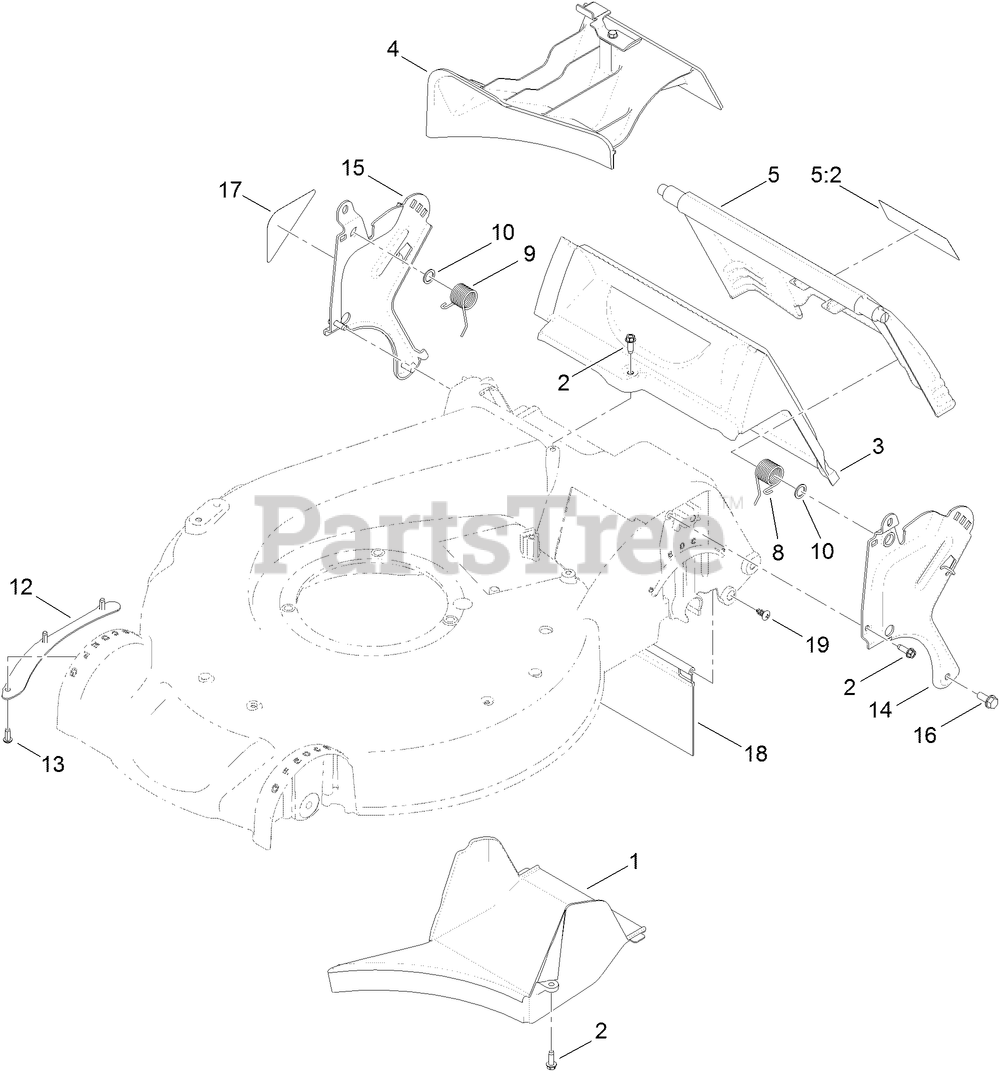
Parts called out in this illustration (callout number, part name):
1	TUNNEL-DISCHARGE
2	SCREW-HWHTF
4	MULCH PLUG ASM
5:2	DECAL-WARNING
8	SPRING-TORSION
9	SPRING-TORSION
10	WASHER-NYLON
12	SHEET-LIP
13	SCREW
14	BRACKET-HANDLE, LH
15	BRACKET-HANDLE, RH
16	SCREW-THD ROLL, HWH
17	DECAL-INSTRUCTION
18	SHIELD-TRAILING
19	SCREW-PTH
